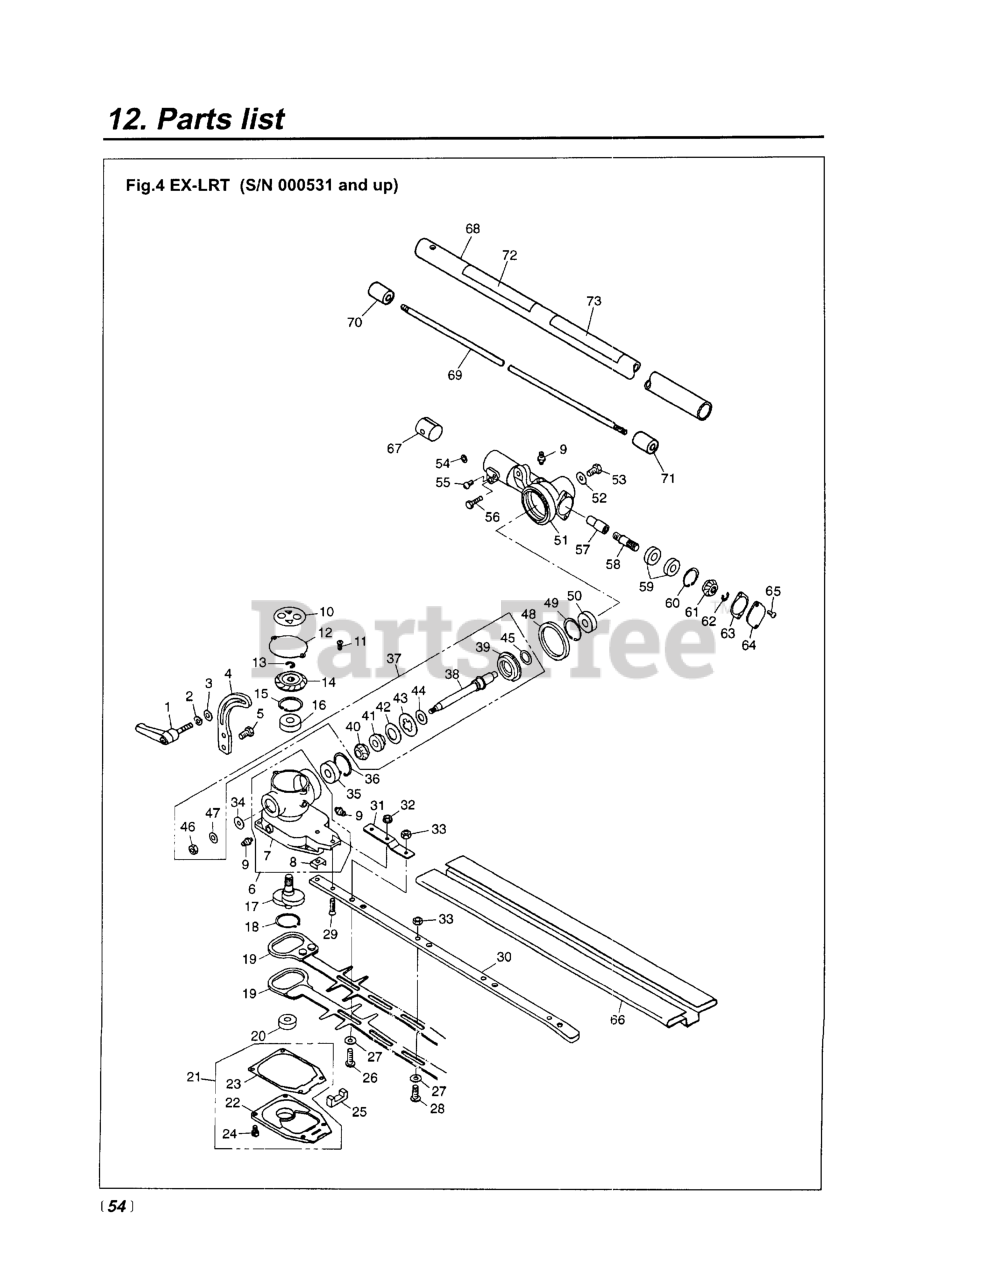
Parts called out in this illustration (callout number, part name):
2	WASHER, M6 X 15
3	WASHER, 6X15X2.0
4	ADJUSTER, ANGLE (USE-13141)
6	CASING (RPLS -13210)
7	CASING A
8	PLATE
9	FITTING, GREASE
11	SCREW, M4 X 8
13	RING, SNAP
14	GEAR, BEVEL
15	RING, SNAP, M26 X 1.2
16	BEARING
17	CRANKSHAFT
18	RING, SNAP, M28 X 1.5
19	BLADE (RPLS -13410) 18
20	BEARING
21	COVER SET (RPLS -13440)
22	COVER
23	GASKET
24	BOLT (RPLS 6782-13450)
25	FELT
27	WASHER (RPLS 3873-11760)
28	SCREW
29	SCREW, M5 X 20
30	PLATE, GUIDE
31	PLATE (RPLS 6780- )
32	NUT, M5
33	NUT, M6
34	WASHER, 6X15X2.0
35	BEARING
36	RING, SNAP, M22 x 1.2
37	KIT, SHAFT (RPLS 6782-13610)
38	SHAFT
39	GEAR (B)
40	GEAR (C)
41	BOSS
42	WASHER, SPRING
43	PLATE
44	WASHER
45	WASHER
46	NUT, M6 X 5
47	WASHER, M6 X 15
48	O-RING
49	RING, SNAP, M26 X 1.2
50	BEARING
51	CASING
52	WASHER, 6X15X2.0
54	WASHER
55	BOLT, M5 X 10
56	BOLT
57	JOINT (REPLACES T3078-13810)
58	SHAFT, GEAR
59	BEARING
60	RING, SNAP, M22 x 1.2
61	GEAR, BEVEL
62	RING, SNAP
63	PACKING
64	COVER, STOPPER KIT
65	SCREW, M4 X 8
66	COVER, BLADE
68	PIPE COMPLETE
69	SHAFT
70	JOINT, SHAFT (RPLS -12240)
71	SPACER
72	PLATE, NAME (LRT-EX)
73	PLATE, CAUTION
